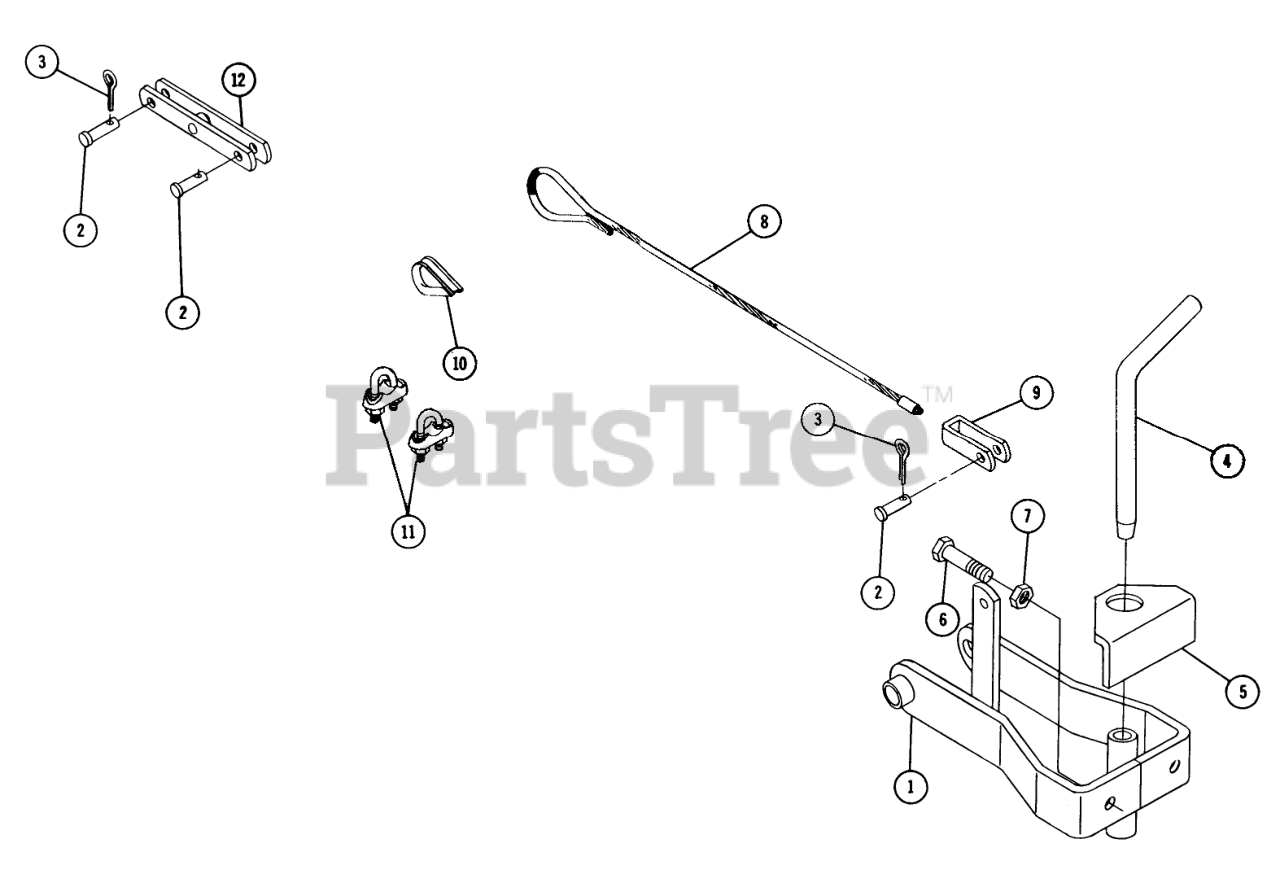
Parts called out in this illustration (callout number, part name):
1	Hitch Ass-y.
3	Cotter Pin
4	Hitch Pin
5	PLATE ADJ HITCH R
6	Bolt 1/2-13 x 2
7	Nut-1/2-13
8	Lift Cable
9	Clevis
10	Thimble
11	U BOLT
12	ASSEMBLY CLEVIS
